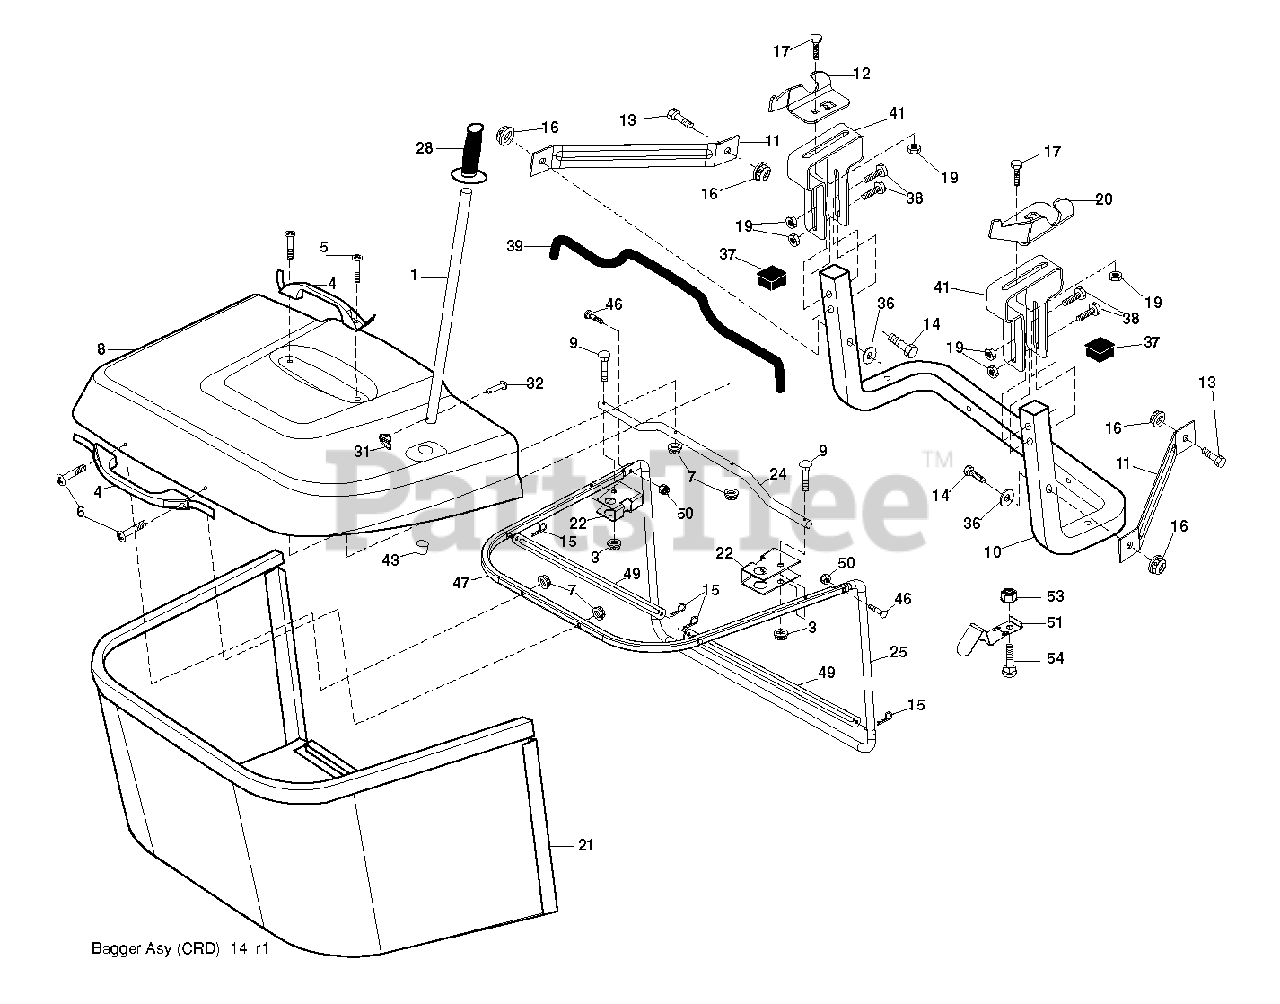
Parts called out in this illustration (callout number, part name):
1	TUBE.PNT.HDL.BAGGER.
3	NUT T
5	SCREW.PAN.HEAD
8	BAGGER.COVER.SEAL.ASM.CRD.428
11	BRACKET
14	BOLT-HEX EAK
15	RETAINER-SPRNG RB
16	NUT LOCK FLG 3/8-16 UNC
17	BOLT
19	NUT LOCK HEX FLANGE 5/16-18
20	BRKT.PIVOT.RH.CRD
21	BAGGER.ASM.CRD.2007
22	BRACKET.BAGGER.SD.
24	TUBE
28	GRIP.HANDLE.BLACK
31	RETAINER CLIP
32	RIVET,DRILLED
38	BOLT.5/16-18X2.5
39	SEAL.BAGGER.CRD
41	BRACKET.BAGGER.SD.
43	PLUG, TUBING END
46	BOLT.CARRIAGE.5/16-18
50	NUT.71038.31-18.HEX.NYLOCK
53	NUT
54	BOLT
